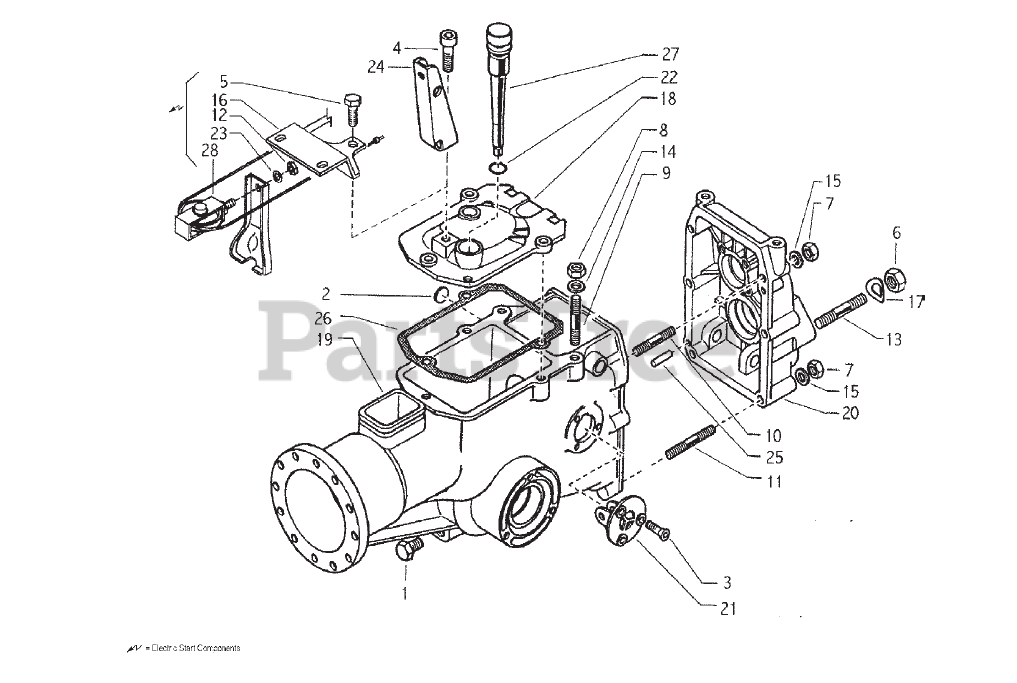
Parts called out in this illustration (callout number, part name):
3	SCREW, COUNTER SUNK, M6X16
4	SCREW M10X25
6	NUT, M12X1.25
7	NUT, SELF LOCKING M8
9	STUDM8X38X14X20
10	STUDM8X58X16X16
11	STUDM8X688X68
13	STUDM12X1.25X12X64
14	SUPER WASHER 8
15	WASHER, LOCK 8.4
17	WASHER, LOCK, M13
18	GEARBOX COVER
19	GEAR BOX CASE
21	REVERSER GEAR COVER, 710
24	CLUTCH BRACKET
25	PARALLEL PIN
26	GASKET, COVER
27	CAP WITH DIP STICK
28	PULLEY ASSEMBLY
